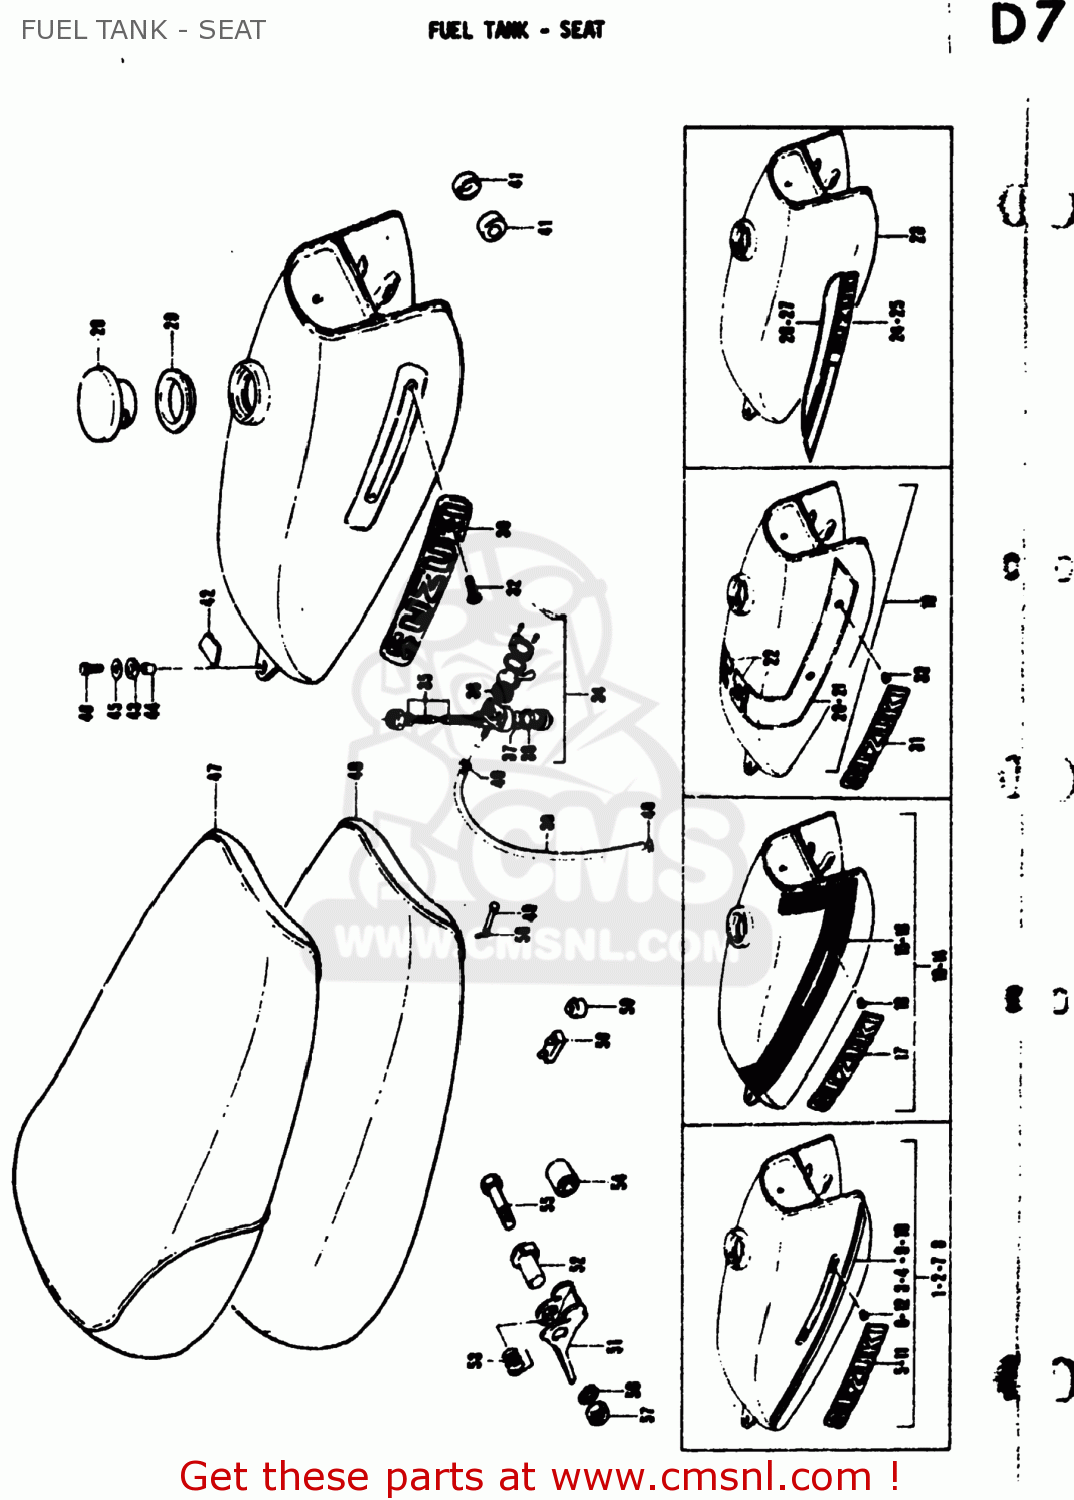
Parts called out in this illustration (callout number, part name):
1	TANK ASSEMBLY,FUEL
2	TANK SET, FUEL TS50R
3	TAPE,FUEL TANK
4	TAPE,FUEL TANK
5	EMBLEM
6	NUT
7	TANK ASSEMBLY,FUEL
8	TANK ASSEMBLY,FUEL
9	TAPE,FUEL TANK
10	TAPE,FUEL TANK
11	EMBLEM
12	NUT
13	TANK ASSEMBLY,FUEL
14	TANK ASSEMBLY,FUEL
15	TAPE,FUEL TANK
16	TAPE,FUEL TANK
17	EMBLEM
18	NUT
19	TANK ASSEMBLY,FUEL
20	TAPE,FUEL TANK
21	TAPE,FUEL TANK
23	TANK ASSEMBLY,FUEL
24	EMBLEM
25	EMBLEM,FUEL TANK
26	TAPE,FUEL TANK
27	TAPE,FUEL TANK
28	CAP SET,FUEL TANK
29	GASKET,FUEL TANK CAP (NAS)
30	EMBLEM
31	EMBLEM, FUEL TANK TS50K
32	SCREW
33	NUT
34	COCK ASSEMBLY,FUEL
35	FILTER SET,FUEL
36	GASKET,LEVER (NAS)
37	NET,STRAINER
38	GASKET,STRAINER CUP (NAS)
39	HOSE
40	CLIP
41	CUSHION
42	CUSHION
43	BUSH(12X15X20)
44	SPACER
45	WASHER
46	BOLT
47	SEAT ASSEMBLY
48	SEAT ASSEMBLY
49	PIN
50	PIN
51	STRIKER,SEAT LOCK
52	STRIKER,SEAT LOCK
53	SPRING
54	BUSHING
55	BOLT 8X45
56	LOCK WASHER
57	NUT
58	CUSHION
59	CUSHION
